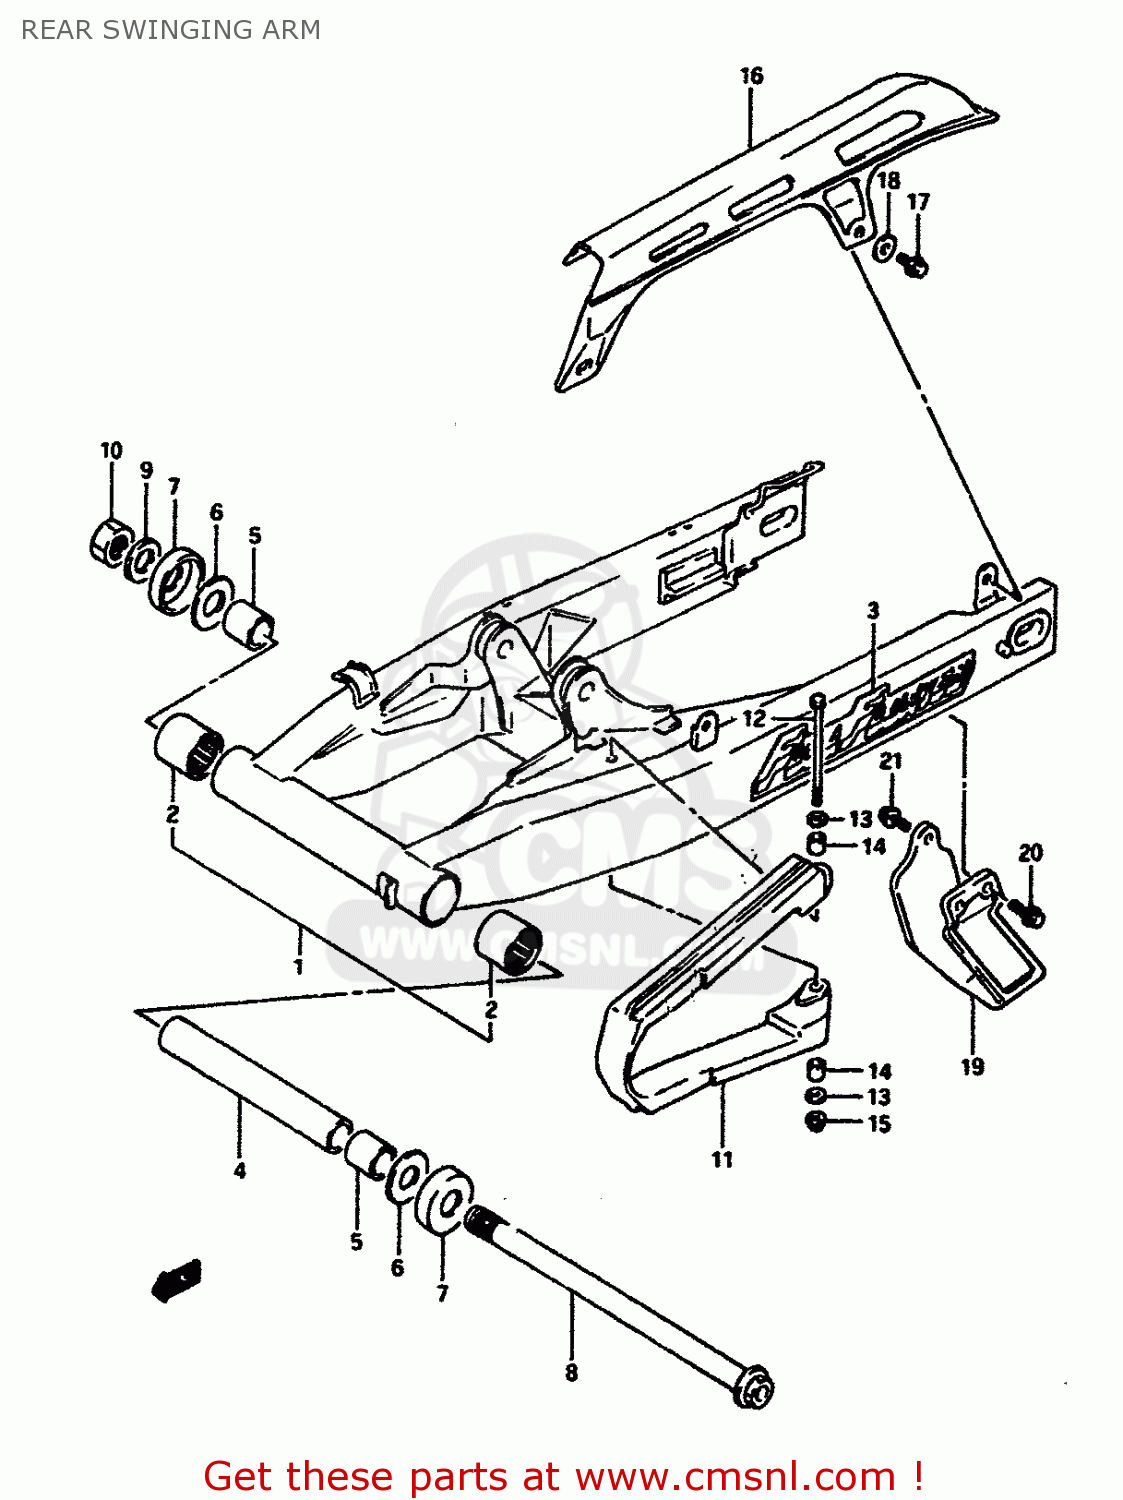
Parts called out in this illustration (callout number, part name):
1	SWING ARM ASSEMBLY,REAR
2	BEARING(22X29X20)
3	EMBLEM
4	SPACER,RR SWGARM PIVOT CTR
5	SPACER,RR SWGARM PIVOT
6	WASHER
7	SEAL,RR SWGARM PIVOT DUST
8	SHAFT,REAR SWING ARM
9	WASHER (BLACK)
10	NUT (BLACK)
11	BUFFER,CHAIN TOUCH DEFLECTOR
12	BOLT,TOUCH DEFENSE FTG
13	WASHER (5.5X14X1.2)
14	SPACER (6.6X9X6.5)
15	NUT
16	CASE,CHAIN
17	BOLT
18	WASHER
19	GUIDE,CHAIN
20	BOLT
21	BOLT 6X16
